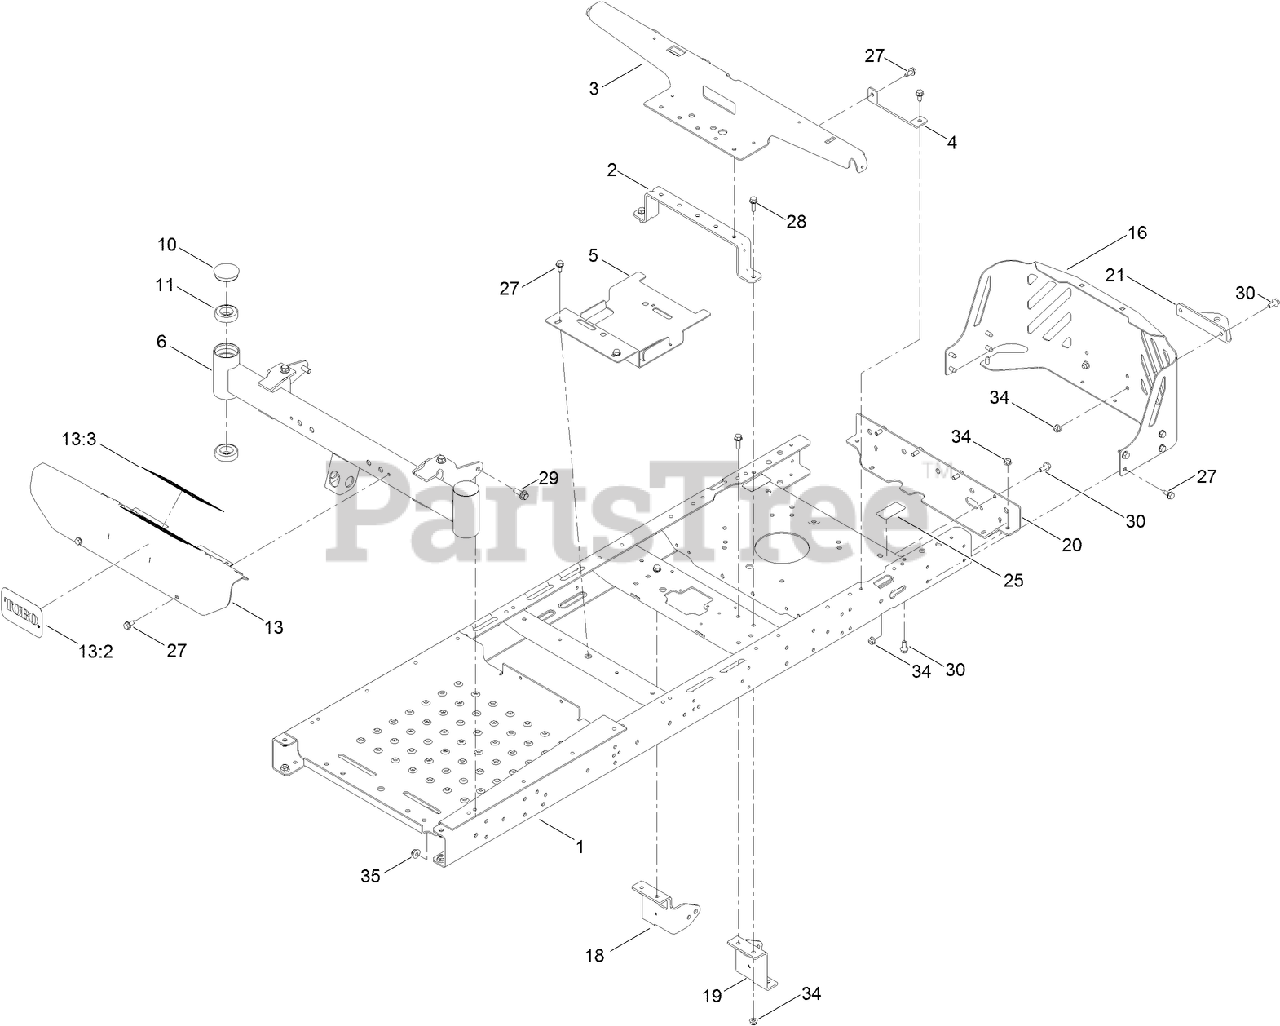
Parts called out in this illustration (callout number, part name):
1	FRAME ASM
2	BRACE-SEAT, REAR (NARROW)
3	SUPPORT-POD
4	SUPPORT-TANK, REAR
5	BRACKET-BATTERY
6	AXLE-FRONT, NARROW
10	CAP-GREASE
11	BEARING-BALL
13	FOOTREST ASM
13:3	DECAL-DANGER
16	GUARD-ENGINE, NARROW
18	MOUNT-HYDRO, FRONT (RH)
19	MOUNT-HYDRO, FRONT (LH)
20	CROSSMEMBER-REAR, NARROW
21	BRACKET-HITCH
25	DECAL-BYPASS
27	SCREW-HWHTF
28	SCREW-HHF
29	SCREW-HHF
30	SCREW-HHF
34	NUT-HF, NI
35	NUT-HF, NI
